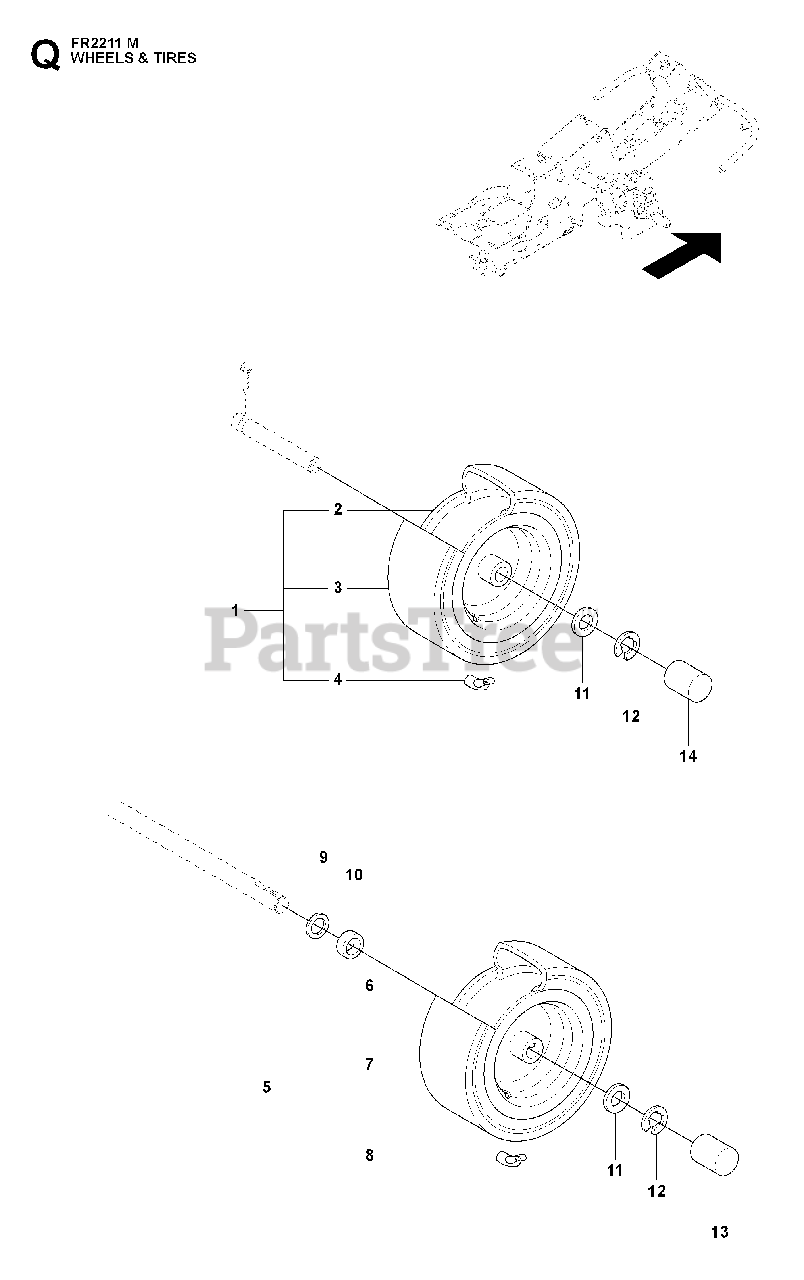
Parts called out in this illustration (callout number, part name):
6	RP RIM
12	RETAINING RING
13	DUST CAP
